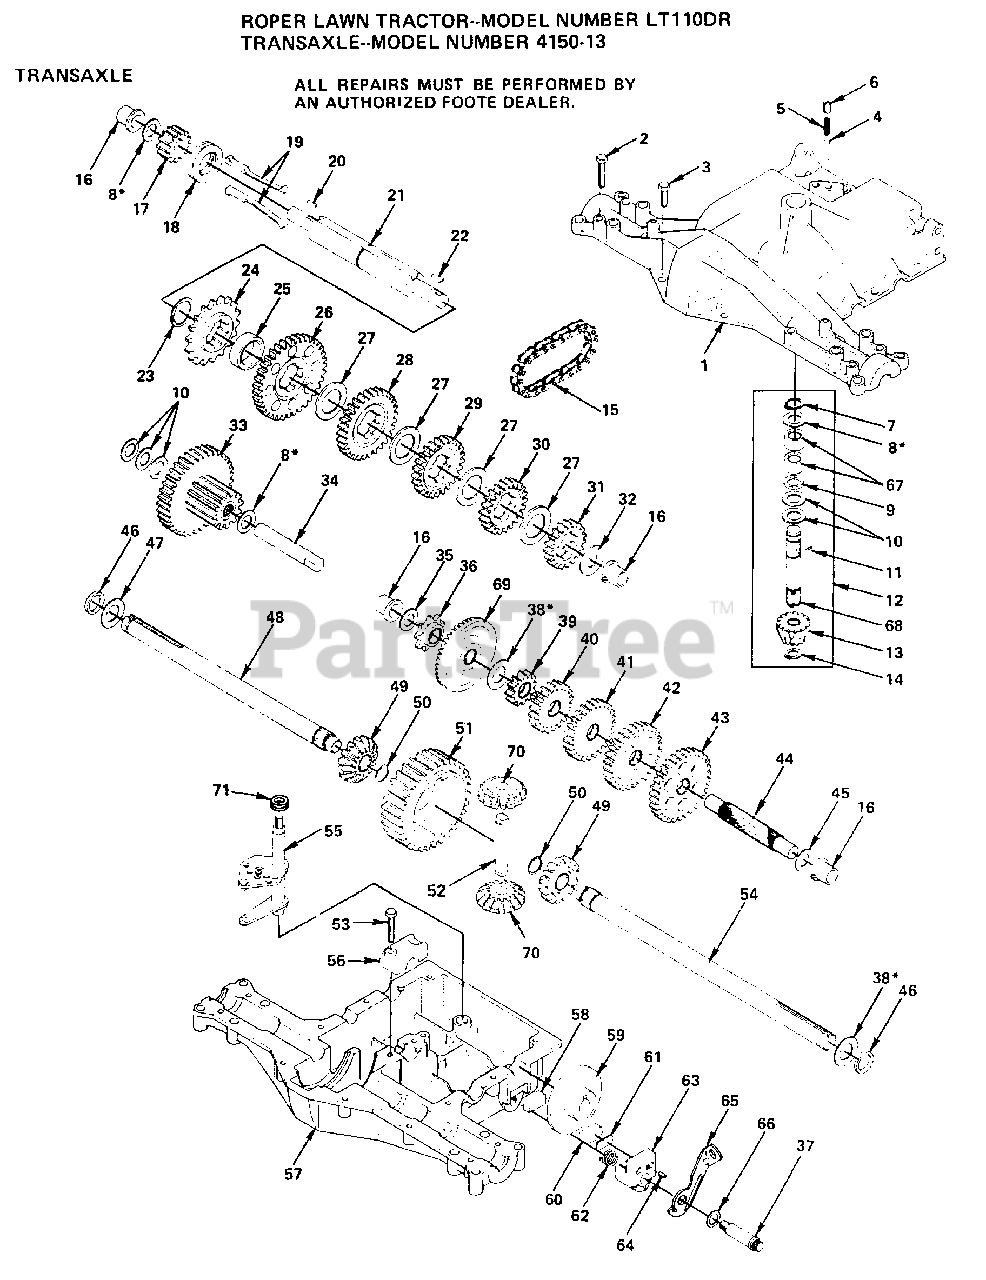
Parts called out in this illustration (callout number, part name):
1	No Desciption for Part
2	SCREW 1/4-20 X 1.31
3	SCREW 1/4-20 X .875
4	BALL DETENT
5	SPRING, DETENT
6	SCREW, SET
7	RING RETAINING
8	WASHER PLAIN
8	WASHER, PLAIN .632 X 1.00 X .026
8	WASHER, PLAIN .632 X 1.00 X .060
10	WASHER PLAIN
11	KEY WOODRUFF #9
12	ASSY KIT INPUT SHAFT
13	PINION BEVEL 14 TEETH
14	RING, RETAINING
15	CHAIN, 24 PITCHES
16	BEARING, FLANGE
17	GEAR, SPUR 14T
18	COLLAR CLUTCH
19	KEY, CLUTCH
20	KEY WOODRUFF #3
21	SHAFT, INTERMEDIATE
22	KEY, WOODRUFF, #61
23	RING, RETAINING
24	SPROCKET, 18T
26	GEAR, SPUR, 37T
27	No Desciption for Part
28	GEAR, SPUR, 30T
29	GEAR, SPUR, 25T
30	GEAR SPUR, 22T
32	WASHER, PLAIN .640 X 1.37 X .061
33	ASSY, GEAR
34	SHAFT, IDLER
35	WASHER PLAIN
36	SPROCKET, 9 TEETH
37	BOLT, SHOULDER
38	WASHER PLAIN
38	WASHER, PLAIN .758 X 1.25 X .031
39	GEAR, SPUR, 12 TEETH
40	GEAR, SPUR 20T
41	GEAR, SPUR, 25 TEETH
42	GEAR, SPUR 28T
43	GEAR, SPUR, 31 TEETH
44	SHAFT, DRIVE
45	WASHER, PLAIN .632 X 1.00 X .060
47	WASHER, PLAIN .758 X 1.25 X .031
49	GEAR, MITER 15T
50	RING, RETAINING
51	GEAR, SPUR, 32T
52	SHAFT, CROSS
53	SCREW TAPPING
55	ASSY, SHIFTER & SEAL
56	CAP, SUPPORT
57	HOUSING, LOWER
58	PUCK, FRICTION
59	DISC, BRAKE
60	PUCK, FRICTION
62	SPRING, COMPRESSION
63	SPRING, COMPRESSION
65	ASSY, LEVER, ACTUATING
66	WASHER, PLAIN
67	BEARING, NEEDLE
69	GEAR, BEVEL, 42 TEETH
70	GEAR, MITER, 15 TEETH
